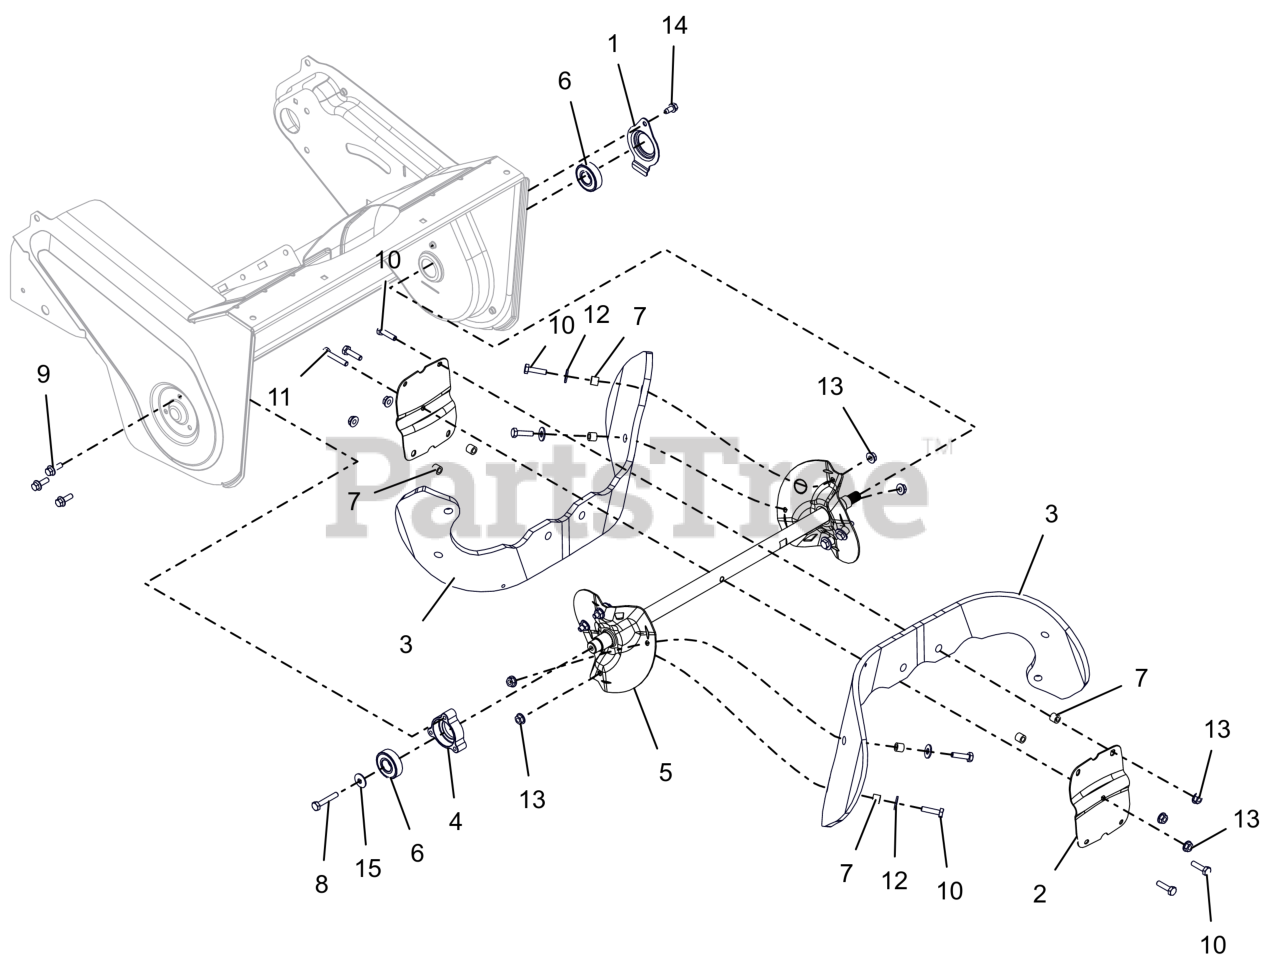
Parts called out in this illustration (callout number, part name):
1	CAP, BRG
2	PLATE, CENTER AUGER
3	FLIGHTING, AUGER
3	KIT, HIGH WEAR PADDLES
4	HOLDER, BEARING - PM
5	AUGER, WELDMENT
6	BRG-BALL .669X1.575X.47(6203Y)
7	BUSHING,.26 ID X .44 OD X .375
8	BLT, HEX .25-20X1.50 G8 ZCC
9	BLT,HEX-FLG .25-20X.75 G5 ZCC
10	BLT,HEX .25-20X1.00 G5 ZCC
11	BLT, HEX .25-20X1.50 G5 ZCC
12	WSHR, FLT .312X.734X.065 ZCC
13	NUT-LK-TOP-FLG .250-20 GF ZCC
14	SCR-TAP .25-20X.50 HWH ZCC
15	WSHR,BLVL-.250X.815X.061 ZFS
